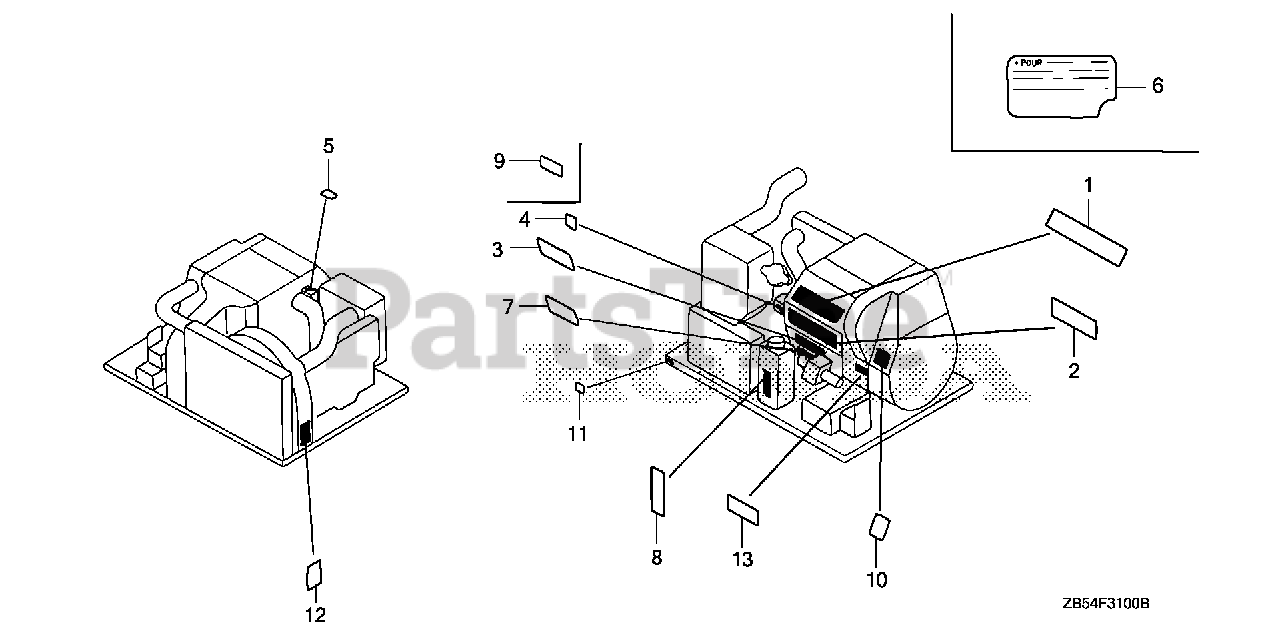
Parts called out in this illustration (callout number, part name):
1	PLATE, INTERVAL WARNING (ENGLISH/FRENCH)
2	EMBLEM (EV6010)
3	PLATE, CONNECT WARNING (ENGLISH/FRENCH)
5	PLATE, AIR CLEANER WARNING
6	LABEL, REMOTE OPENER (FRENCH)
8	MARK, COOLANT INDICATION (ENGLISH/FRENCH)
9	PLATE, INSTALLATION WARNING (ENGLISH/FRENCH)
10	MARK, OIL CAUTION
11	MARK, GRAND
12	PLATE, SET UP CAUTION (ENGLISH/FRENCH)
